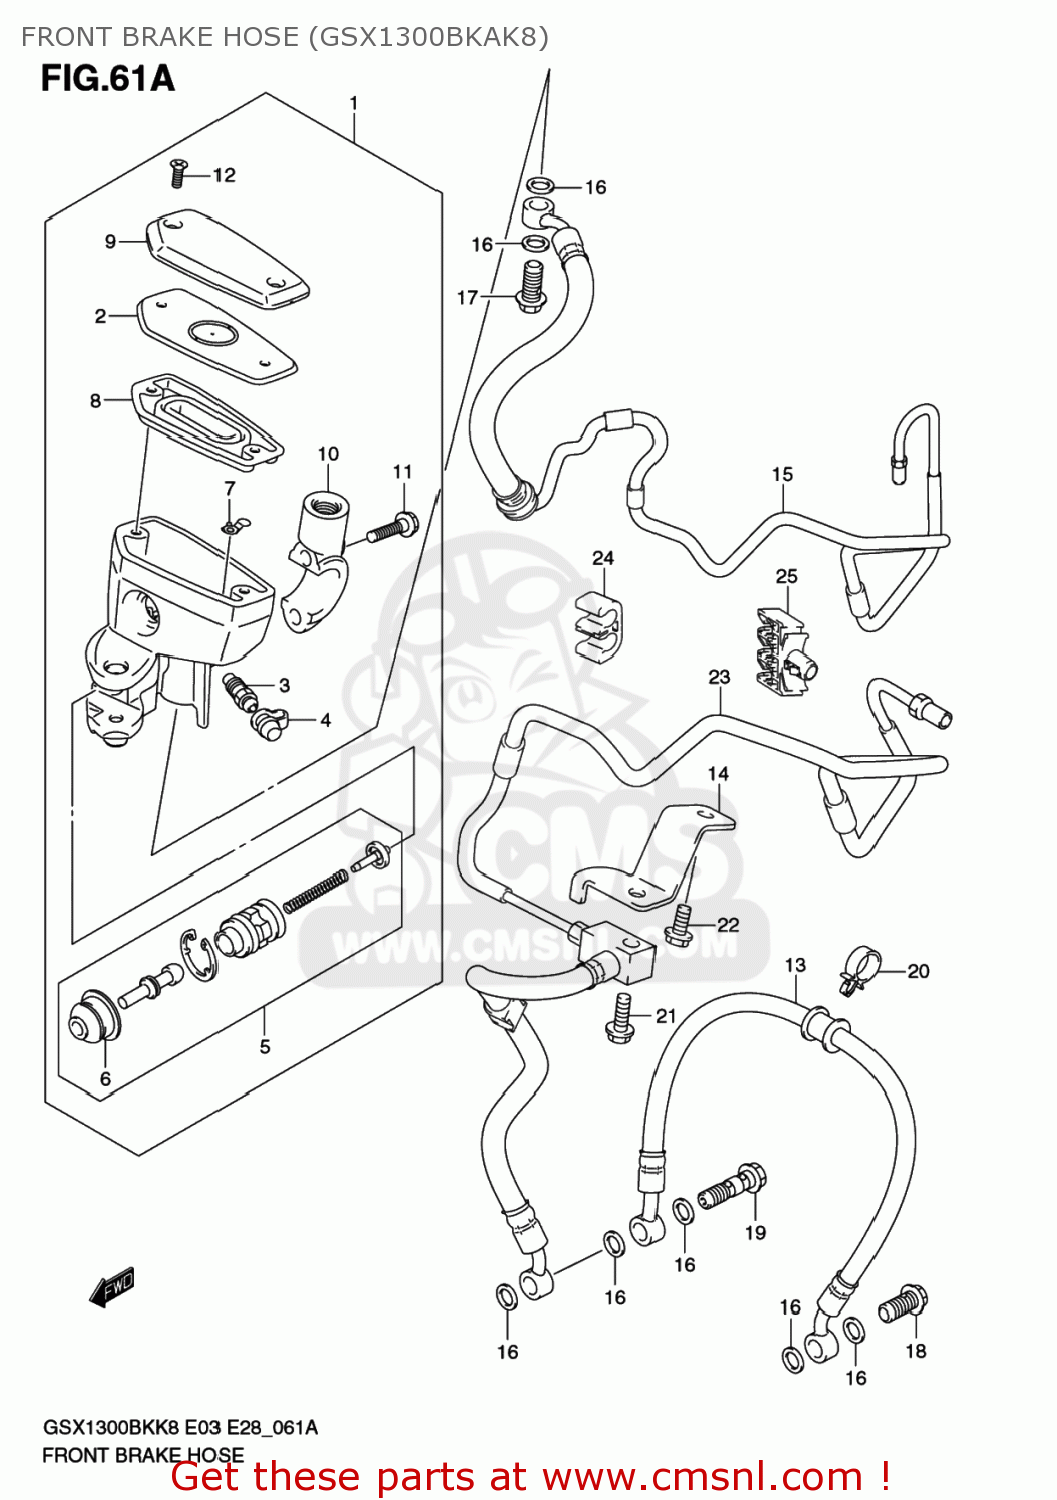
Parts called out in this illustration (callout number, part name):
1	CYLINDER ASSY,FR MASTER
2	PLATE
3	BLEEDER
4	CAP,BLEEDER
5	PISTON / CUP S
6	BOOT
7	PROTECTOR
8	DIAPHRAGM,R
9	CAP
10	HOLDER
11	BOLT(6X22)
12	SCREW
13	HOSE,FR BRAKE NO.2
14	CLAMP,FR BRAKE HOSE NO.2
15	HOSE ASSY,FR BRAKE NO.1
16	WASHER(10X15X1.5)
17	BOLT UNION
18	BOLT UNION
19	BOLT UNION
20	CLAMP
21	BOLT
22	BOLT
23	HOSE ASSY,FR BRAKE NO.2
24	CLAMP
25	CLAMP
